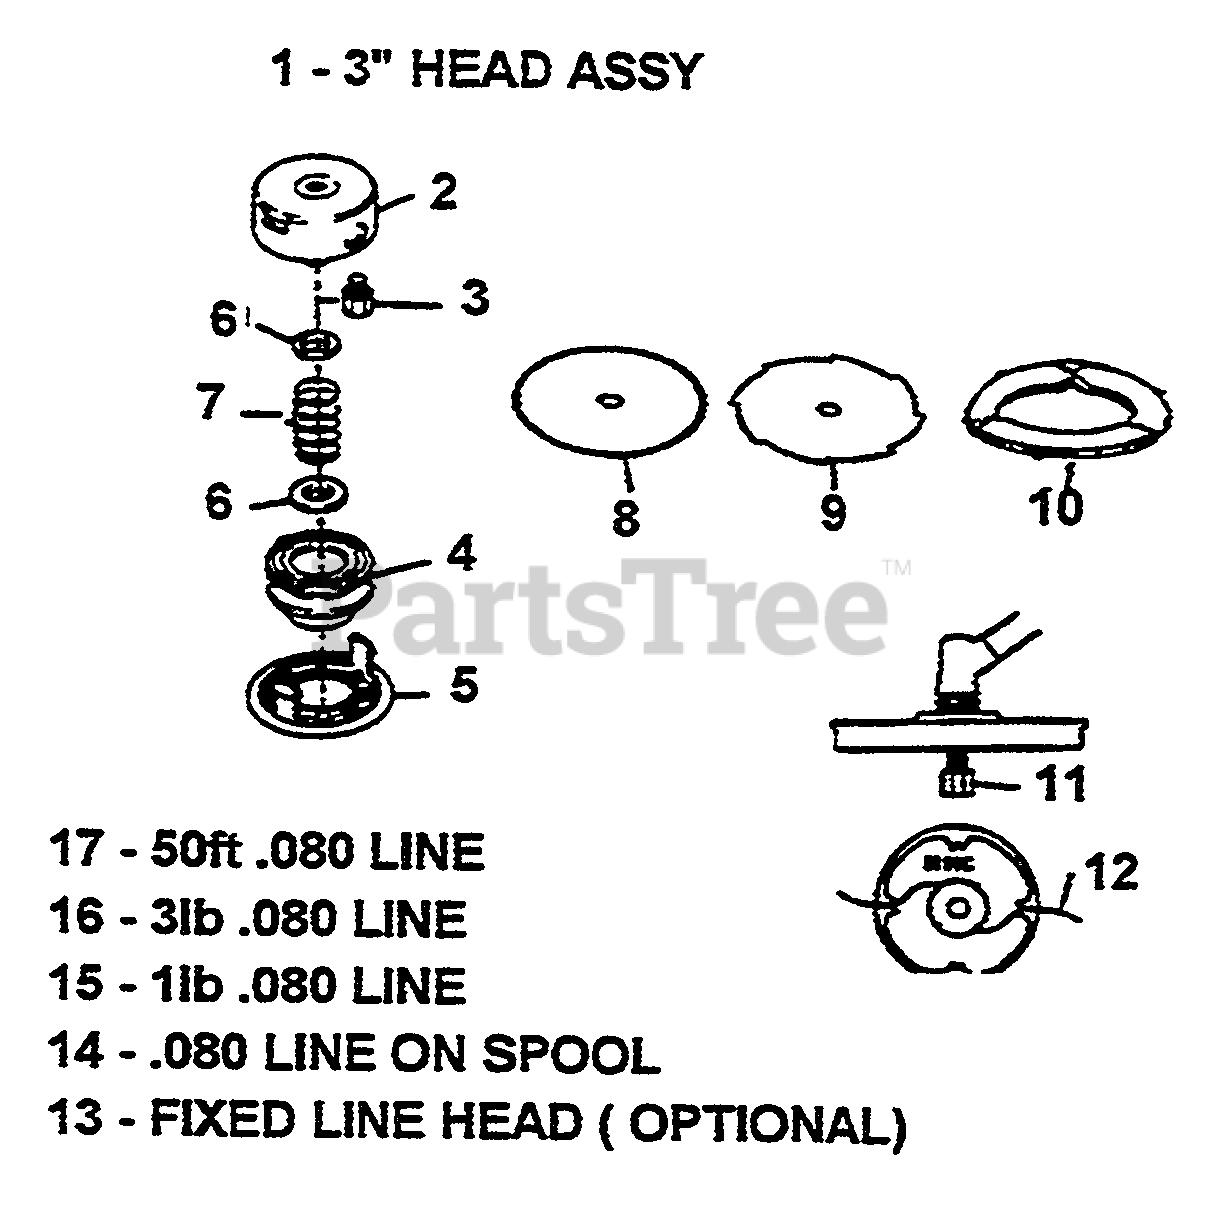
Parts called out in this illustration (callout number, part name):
1	3" HEAD ASSY
2	BODY
3	ARBOR BOLT
5	CAP
6	PLATE, SPRING
7	SPRING
8	8" SAW BLADE
9	8" BRUSH BLADE
10	BLADE COVER
11	ARBOR BOLT
12	.105 LINE, 20" STRIPS
13	FIXED LINE HEAD
14	SPOOL & LINE
15	1 lb .080 LINE
16	3 lb .080 LINE
17	50 ft .080 LINE
